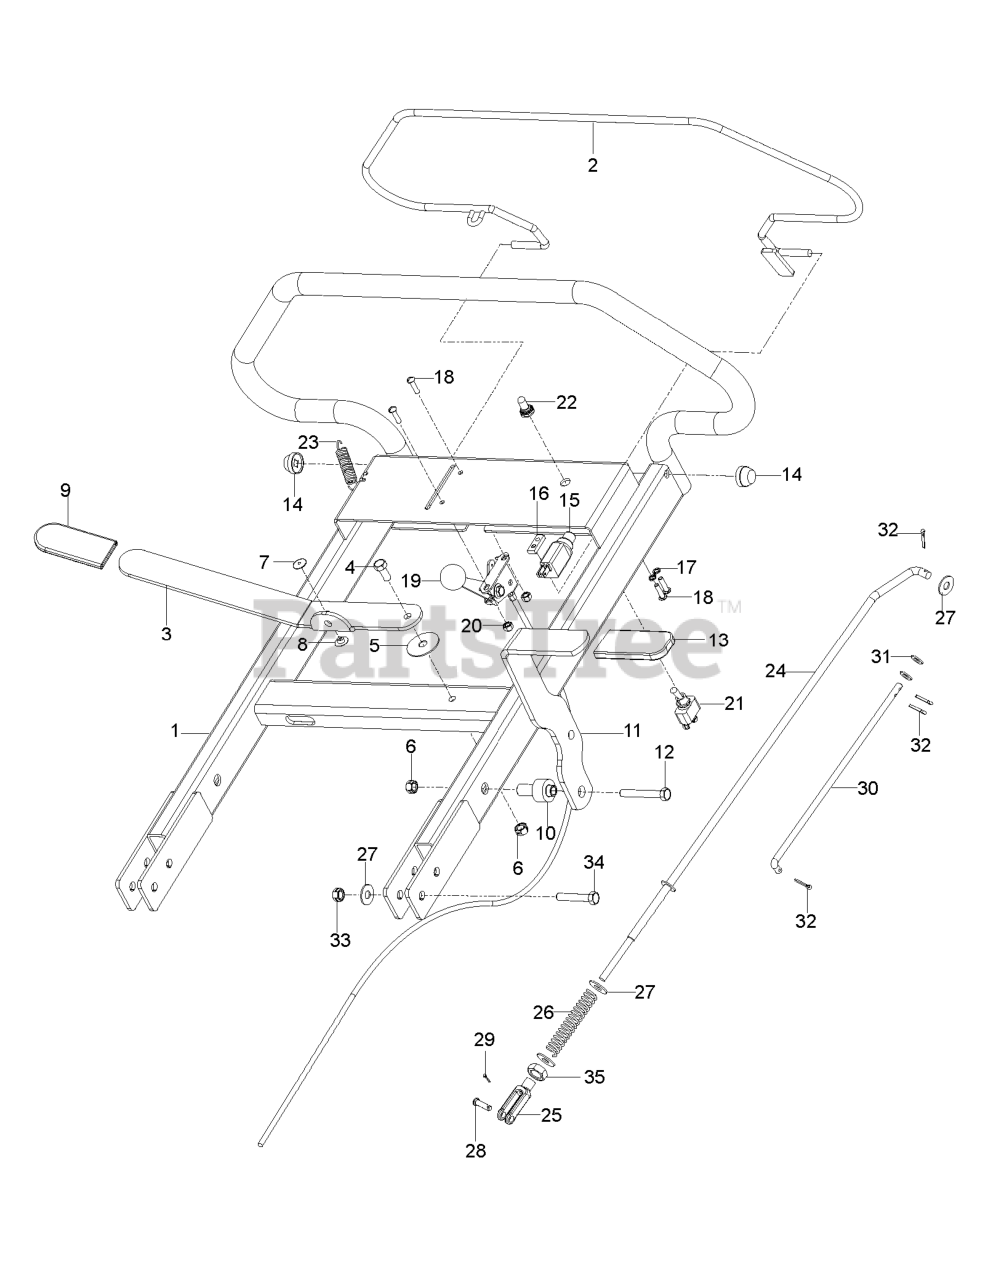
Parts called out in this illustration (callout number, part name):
1	HANDLE.UP.DST.SS/VS.FG/RGD.CRE
2	CABLE.MZR.FGD.PLUS
3	BRACKET.UPSTOP.RT
6	KNOB.HANDLE.PLASTIC.STAR.BLACK
8	RP BAIL.OVER.MOLD.STRAIGHT.ORG
9	DOOR.REAR.ASM.22+.HUSQ.FG/RGD
11	COTTER.HAIRPIN.DOOR/HANDLE.PIV
12	KNOB, DEFLECTOR
13	PLUG.PLASTIC.7/8".14-20.GAUGE
17	BAFFLE.22PLUS.FGD.REAR.
18	NUT
19	RB GUIDE.ROPE.STD.BLK.ZIN WSL
20	SKIRT.REAR.22PLUS.RGD/FGD.NEW
21	SPRING.LH.BLACK
22	SCREW.PAN.HEAD.#10
24	SPRING.RH.GRAY
25	NUT.HEX.FLANGE.3/8-16.LO(3 2)
26	SCREW,DOOR/HANDLE.PIVOT
27	WHEEL & TIRES ASSY, FRONT
28	BOLT
31	SELECTOR KNOB
32	LATCH.DOOR.ZINC
33	DOOR.MULCH.22 PLUS.HUSQ.GREY
34	BRACKET.GRASSBAG.ATTACHING.BLK
35	ADJUSTER.ASM.9POS.LW.RR/RGD.
36	BRACKET.ASM.HINGE.21.FWGD.
38	DEFLECTOR.CLIPPING.22.BLACK
39	BRACKET.ASM.HNDL.LT.22+.GREY
40	BRACKET.ASM.HNDL.RT.22+.GREY
41	BOLT 3/8-16X1-1/8
42	SPRING.TORSION
43	NUT.HEX.FLANGE.1/4
44	HOUSING.22+.FWD.MC.ZWO.ORANGE.
45	ROD.HINGE.21
46	ADAPTOR.BLADE.7/8".STAR
47	BLADE.22+4N1.2PIN.5STAR.(P07)
48	WASHER,HARDEN
49	LOCKWASHER
50	SCREW, HEX HD 3/8-24 X 1-3/8
51	BAFFLE.FRONT.22.PLUS
52	DANGER DECAL
53	BOLT.5/16HEX.WHS.HD
54	WASHER.FLAT.1/2
55	NUT.HEX.FLANGE.1/4
56	SCREW.HX.13X.750
57	NUT.FLANGE.5/16
58	HANDLE.LOWER.22+BT.2PC.GRY
59	BOLT, HANDLE 5/16-18X1.75
62	BRACKET.ENG/BELTKEEPER
65	O-RING..070X.487.NEOPRENE
68	ADJUSTER.ASM.9POS.LW.RL/RGD.FR
83	TAPPING SCREW
84	FASTENER.PUSH.O.250X0.783
85	BRACKET.SKIRT.22+.BZP
96	CLIP.CABLE.BLK
